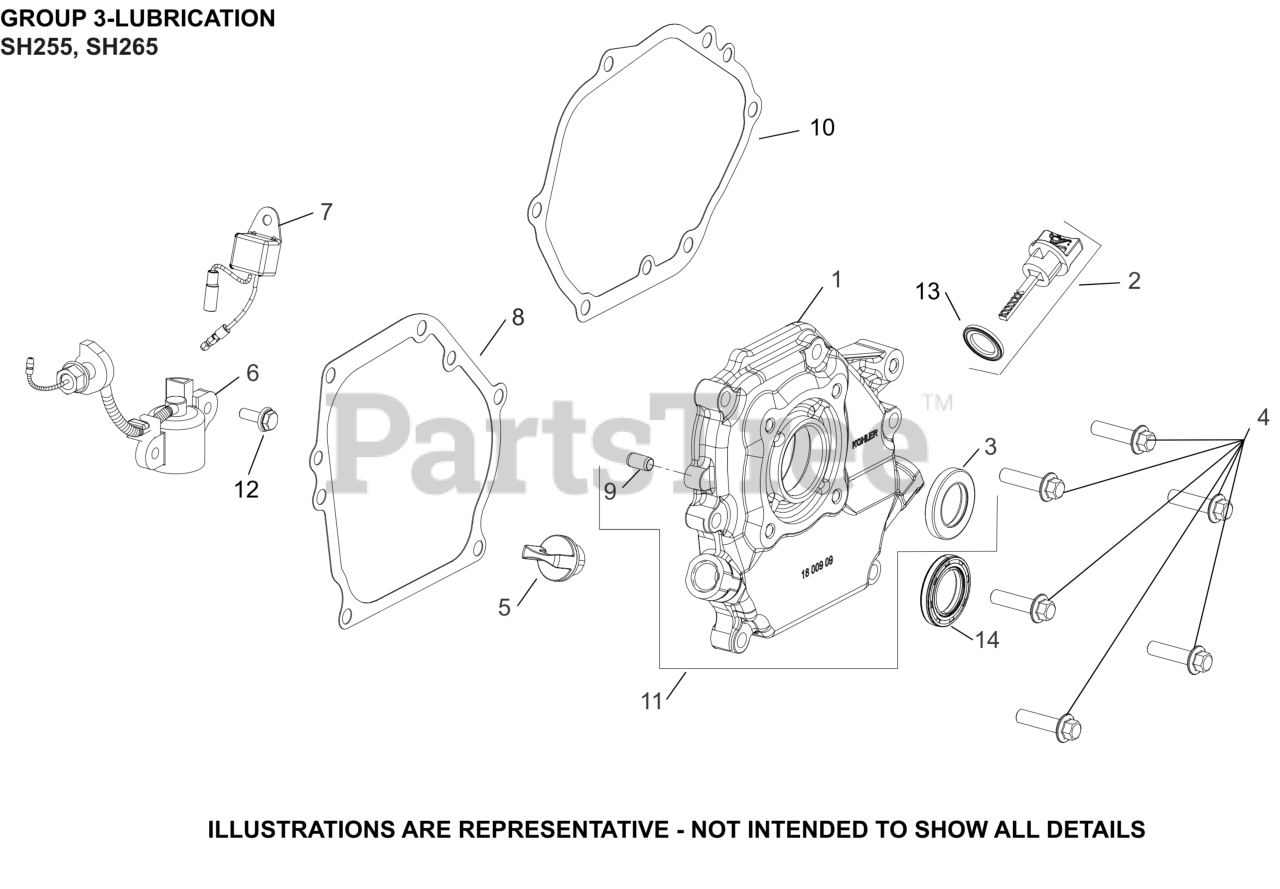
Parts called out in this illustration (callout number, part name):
1	PLATE, CLOSURE & BEARING
2	DIPSTICK ASSEMBLY
3	SEAL, DIPSTICK
3	SEAL - USE 17 032 29-S
4	SCREW, CLOSURE PLATE
6	SWITCH, OIL SENSOR ASSEMBLY
7	CONTROL, OIL ALERT UNIT
NI	SCREW, M6 X 16
